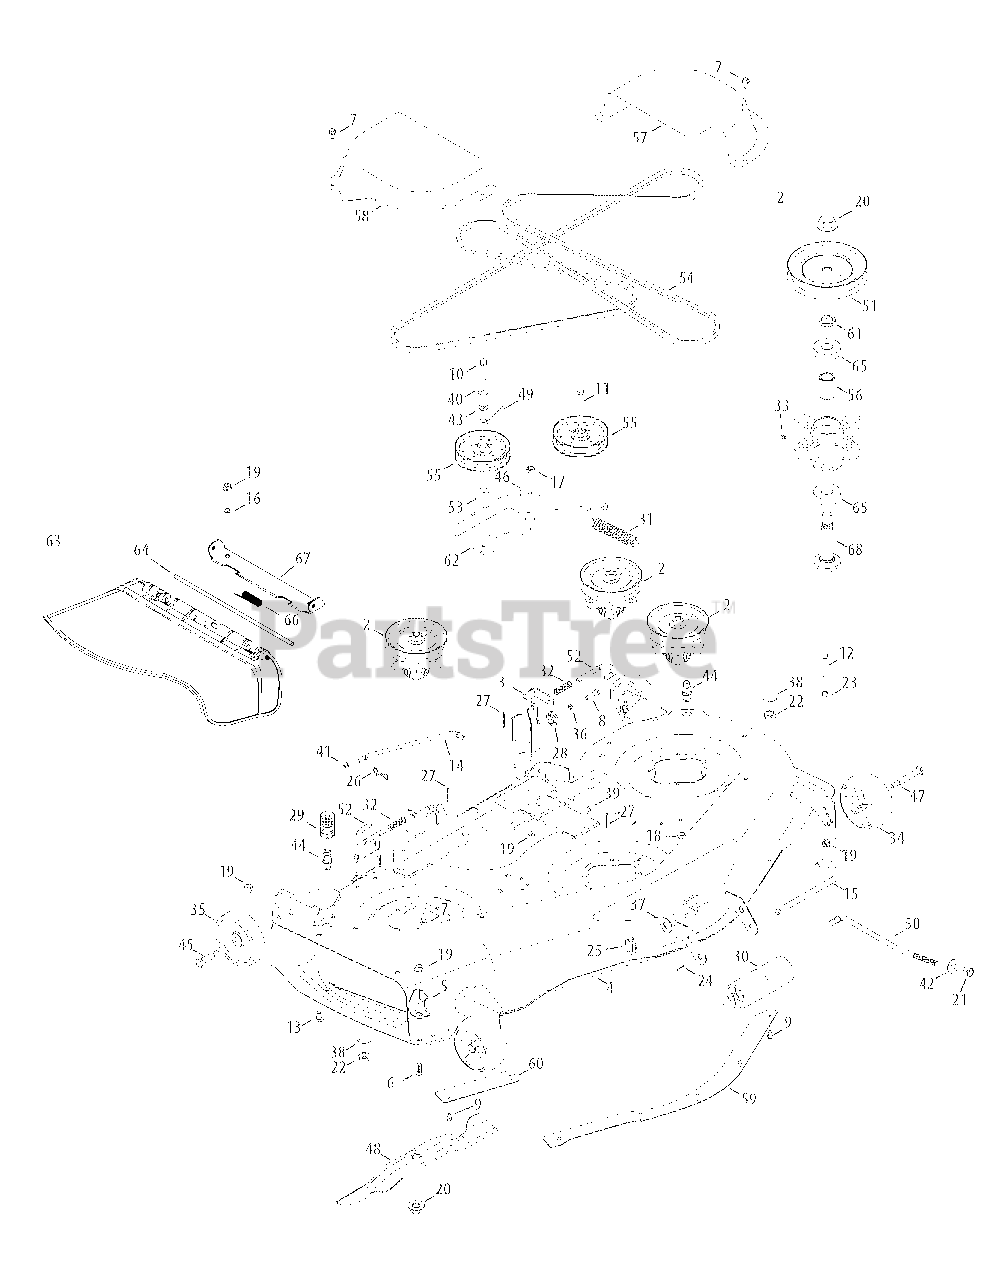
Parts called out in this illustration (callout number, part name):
1	Bracket, Hook, Retainer
2	Spindle Assembly, Pulley, 5.3 Dia.
3	Bracket Assembly, Deck, Hanger LH
4	Deck, 50"
5	Stop, Chute, Dfl
6	Hex Screw, 3/8-16, 1.00, Gr5, Spec
7	Screw, Self-tapping, 5/16-18, .750,
8	Hex Screw, 5/16-18, 1.25, Gr5, Std
9	Screw, Self-tapping, 1/4-20, 0.500
10	Screw, Hex Washer, 3/8-16, 1.875
11	Hex Screw, 3/8-16, 2.25, Gr5, Std
12	Hex Screw, 5/16-18, 2.00, Gr5, Std
13	Bolt, Carriage, 3/8-16, 0.75, Gr1
14	Rod, Support, Deck
15	Roller Pin-1/2 Dia. x 7.31
16	Nut, Push, 3/8
17	Nut, Jam, 7/16-20, Gr2
18	Nut, Flange Lock, 5/16-18, Nylon
19	Nut, Flange Lock, 3/8-16, Nylon
20	Nut, Flange, 5/8-18
21	Nut, 1/2-13
22	Nut, Hex, M16-1.5
23	Nut, Hex, 5/16-18, Gr5
24	Pin, Cotter, 3/32, 1.0
25	Pin, Lynch, .1875
26	Pin, Cotter, Bow-Tie
27	Pin, Cotter, 1/8 x 1.25
28	Gear, Deck, Adjustment
29	Coupler, Water
30	Roller, Front
31	Spring, Extension, 1.0 OD x 6.10
32	Spring, Compression, .535 OD x 1.751
33	Lube Fitting, 3/16
34	Wheel, Deck, 5.0 Dia. Ball
35	Wheel, Deck 5.0 x 1.38
36	Washer, Lock, 5/16, Regular Duty
37	Washer, Flat, .531 x 1.25 x .100
38	Washer, Lock, 5/8, Int Tooth
39	Washer, Flat, .344 x .688 x .065
40	Washer, Flat, .406 x .875 x .059
41	Washer, Thrust, .375 x .70 x .030
42	Washer, Bell, .63 x 1.25 x .18
43	Washer, Flat, .407 x .812 x.135
44	Port, Water
45	Bolt, Shoulder, .496 x 1.525, 3/8-16
46	Spacer, Shoulder, .8840 x .190
47	Bolt, Shoulder, .496 x 2.50, 3/8-16
48	Blade, 17.90 Star 2 In 1
49	Rod, Keeper,
50	Rod, Lift, Deck, Front, 11.7
51	Pulley, Deck, 5.39 Dia.
52	Rod, Deck Release
53	Spacer, .406 Id x 1.00 OD x .38
54	Belt, V-Type
55	Pulley, Idler, 4.25"Dia.
56	Spacer, .800 x 1.100 x 1.5300
57	Cover, Belt, LH 50"
58	Cover, Belt, Rh 50"
59	Skirt, Center, 50"
60	Skirt, RH, 50"
61	Spacer, .750 x 1.150 x .230
62	Bracket, Idler, Arm
63	Chute Assembly
64	Pin, Hinge, .3175 Dia. x 14.06 ,1
65	Bearing, Ball, .787id x 1.85 Odx.551
66	Spring, Torsion, .44 I.D. x 2.0,
67	Bracket, Chute 50/54"
68	Shaft, Spindle, 4.1250
